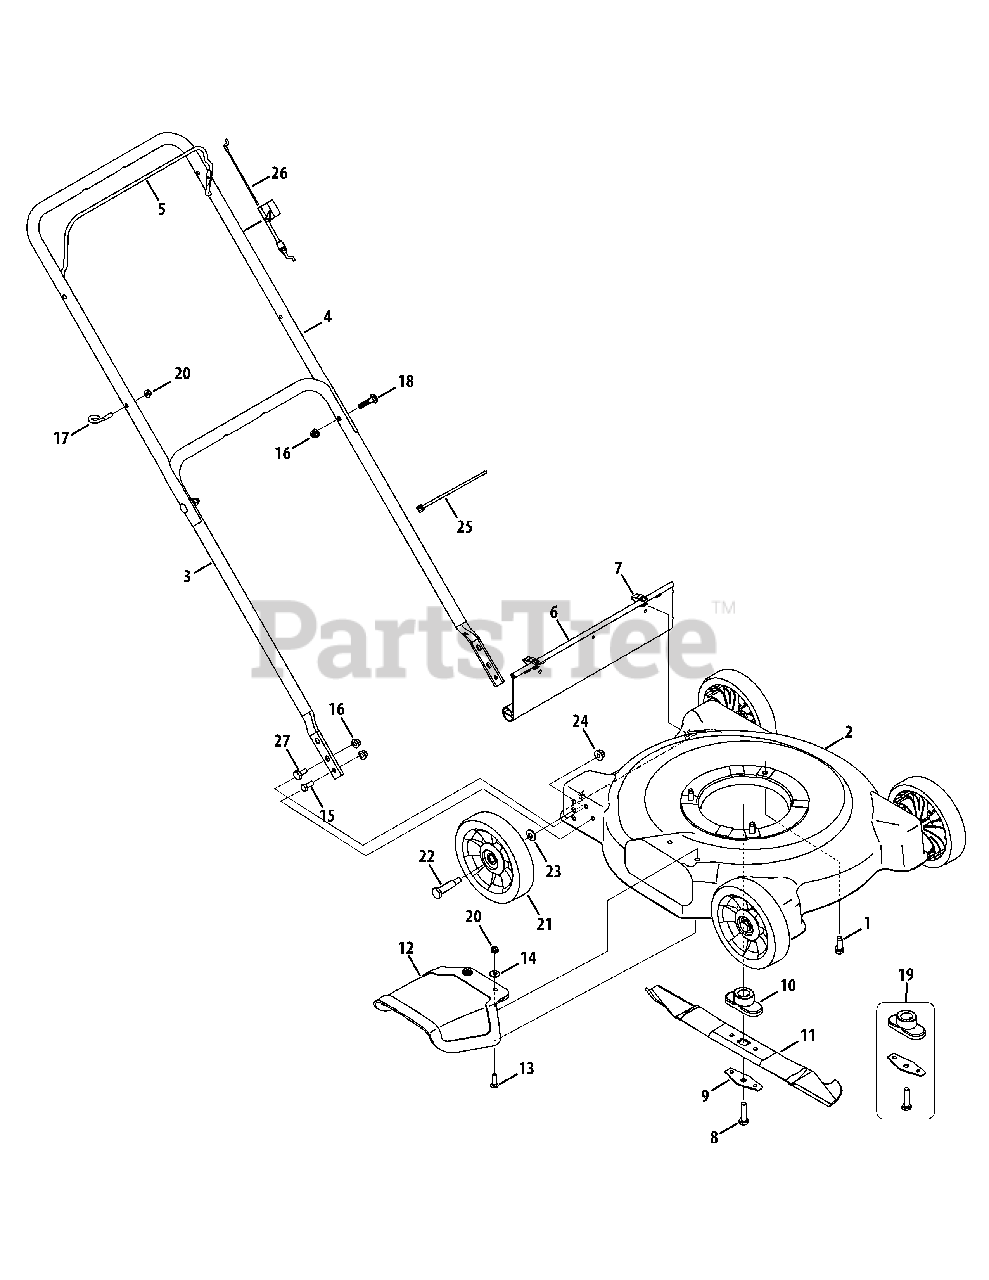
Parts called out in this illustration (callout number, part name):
1	Hex Ind. Washer Screw, 3/8-16 x 1.0
2	Cutting Deck, 20"
4	Upper Handle
5	Blade Control
6	Rear Flap
7	Hinge Clip
8	Screw, 3/8-24 x 1.5"
9	Blade Bell Support
10	Blade Adapter
11	Cutting Blade
12	Discharge Chute
13	Carriage Screw, 1/4-20 x 1.0"
14	Flat Washer
15	Hex Screw, 5/16-18 x .75"
16	Flange Lock Nut, 5/16-18
17	Eye Bolt
18	Carriage Bolt, 5/16-18 x 1.5"
19	Blade Adapter Kit (Incl. Ref. 8-10)
20	Flange Lock Nut, 1/4-20
21	Wheel, 7" Star-Dia., Oys. Gray
22	Shoulder Screw, .498 x 1.635
23	Bell Washer
24	Flange Lock Nut, 3/8-16
25	Cable Tie
26	Control Cable, 148cc, 37.25"
26	Control Cable, 139cc, 48"
27	Shoulder Screw, 5/16-18 x.428"
